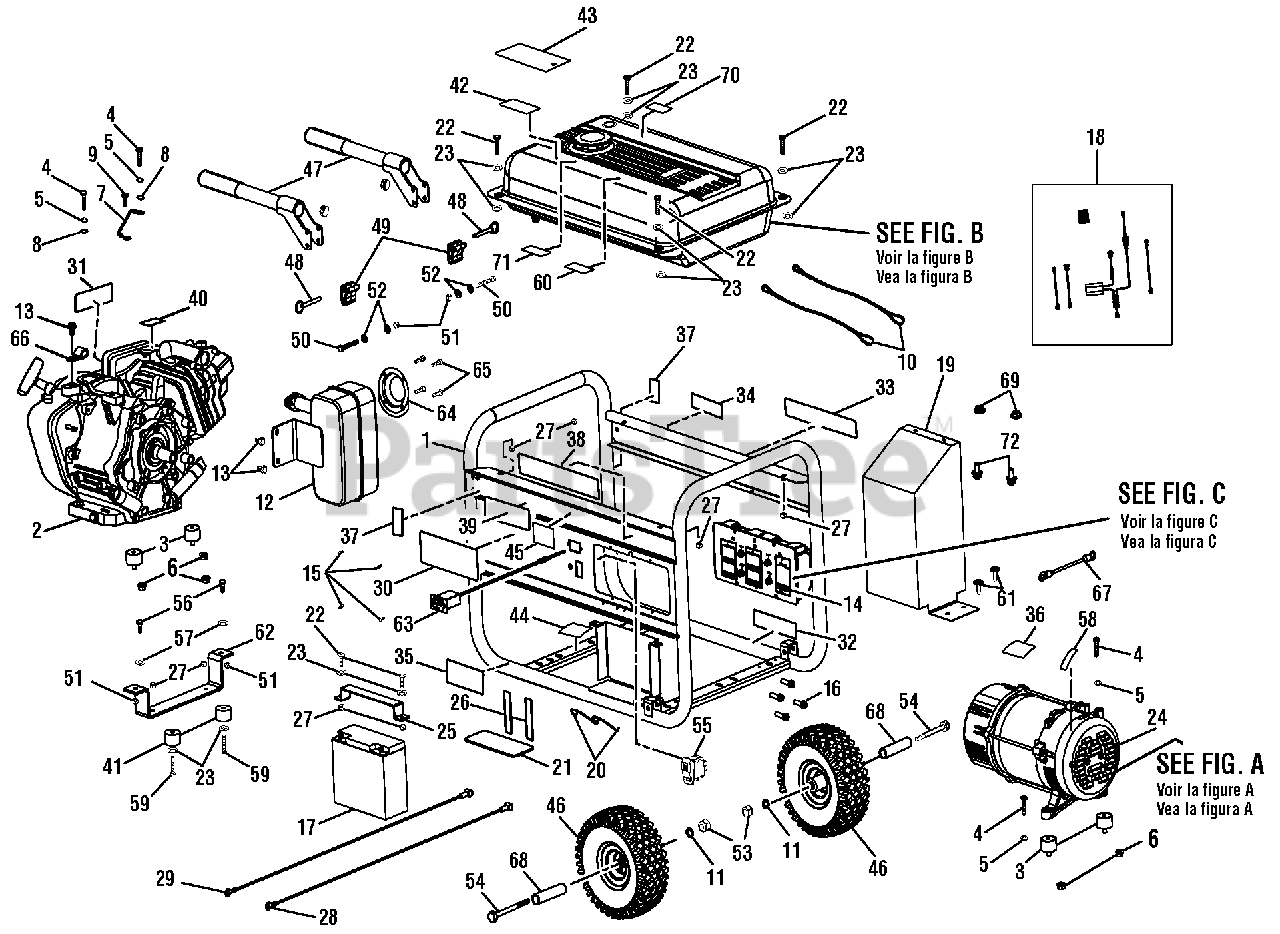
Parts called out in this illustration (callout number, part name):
1	Carrier Assembly
4	Bolt (5/16-18 x 1-1/2 in., Hex Hd.)
5	Lock Washer (5/16 in.)
6	Flange Nut (5/16-18, Hex Hd.)
7	Ground Wire Assembly
8	Star Washer (5/16 in.)
9	Bolt (5/16-18 x 3/4 in., Hex Hd.)
10	Lanyard (3/16 in.)
11	Washer (3/8 in)
13	Bolt (5/16-24 x 5/8 in.)
14	Control Panel Assembly
15	Screw (6-20 x 3/8 in.)
16	Bolt (3/8-16 x1.25 in.)
17	Battery
18	Wire Harness
19	Heat Shield
20	Cord Retainer
21	Battery Box Gasket
22	Bolt (1/4-20 x 1 in., Hex Hd.)
23	Washer (1/4 in.)
24	Generator Head w/AVR
25	Battery Hold Down Bracket
26	Gasket (Battery Hold Down Bracket)
27	Lock Nut (1/4-20)
28	Battery Cable (Red)
29	Battery Cable (Black)
30	Logo Label
31	Electric Start Label
32	Hot Surface Label
33	Danger Label
34	Fire Danger Label
35	Engine Lubricant Label
36	Data Plate Label
37	Locking Pin Label
38	Yamaha Label
39	Electric Start Label
40	Choke Label
41	Rubber Feet
42	CPSC Label
43	Danger Hang Tag
44	Inquires Label
45	Combustion Warning Label
47	Handle Assembly
48	Release Pin (5/16 x 2 in.)
49	Handle Bracket Spacer
50	Bolt (5/16-18 x 1-1/2 in., Hex Hd.)
51	Lock Nut (5/16)
52	Washer (5/16 in.)
53	Lock Nut (3/18-16)
55	Start Switch w/Lock
56	Bolt (5/16-18 x 1 in., Hex Hd.)
57	Flat Washer (5/16 in.)
58	Ground Label Icon
59	Bolt (1/4-20 x 1-1/2 in., Hex Hd.)
60	Mexico Support Label
61	Screw (8 x .75 in.)
62	Front Foot
63	Voltage Meter
64	Spark Arrestor
65	Screw (8-32 x 3/8 in., Pan Hd.)
66	J-Clamp (1/2 in.)
67	Bonding Wire
69	Flange Nut (M6)
70	E85 Label
71	Fire Distance Label
72	Bolt (M6 x 12 mm)
